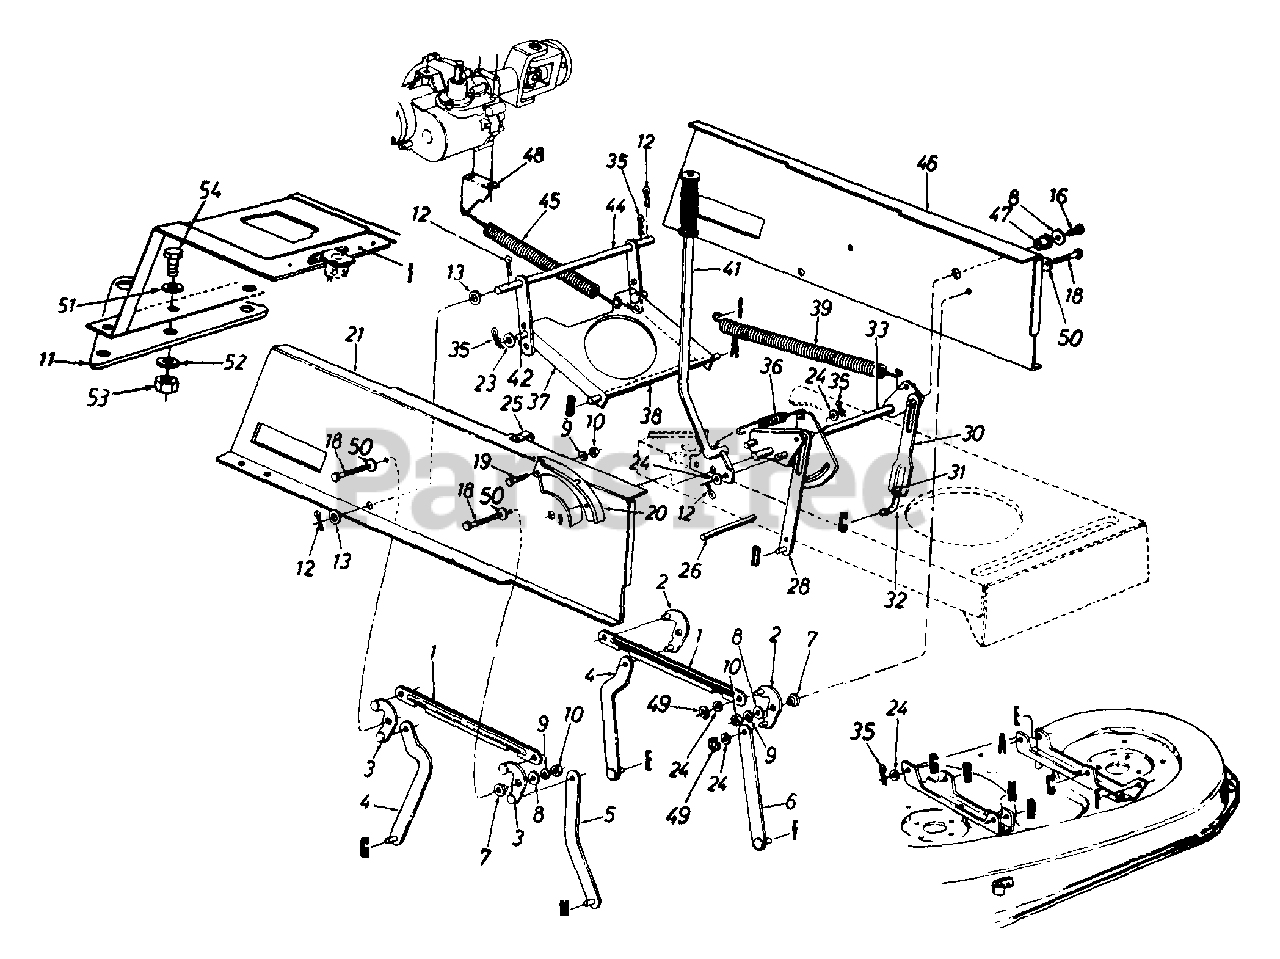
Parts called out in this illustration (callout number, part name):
3	Pivot Link Ass'y. - R.H.
7	Shld. Spacer .318" I.D.
8	Fl-Wash. .344" I.D. x .62" O.D.
9	L-Wash. 5/16" I.D.
10	Hex Nut 5/16-18 Thd.
11	Hitch Plate Extension
12	Cotter Pin 1/8" Dia.
13	Fl-Wash. .635" I.D. x 1.0" O.D.
16	Hex Wash. TT-Tap Scr. 5/16-18 x .75" Lg.
18	Hex Wash. Hd. Scr. 5/16-18 x .875" Lg.
19	Hex Bolt 5/16-18 x .75" Lg.
20	Index Brkt.
21	Upper Frame - R.H.
23	Fl-Wash. .385" I.D. x .87" O.D.
24	Fl-Wash. .531" I.D. x .93" O.D.
26	Running Board Rod
31	Hex Nut 1/2-20 Thd. (Gr. 5)
32	Lift Link Adjuster
33	Lift Shaft Ass'y.
35	Inter. Cotter Pin 3/8" Dia.
36	Extension Spring
39	Extension Spring
41	Deck Lift Handle Ass'y.
42	Weld Pin
44	Stabilizer Shaft Ass'y.
45	Extension Spring 7.58" Lg.
46	Upper Frame - L.H.
47	Flange Brg. .632" I.D.
49	"E"-Ring
50	Bell-Wash. .325" I.D.
51	Bell-Wash. .46" I.D.
52	Fl-Wash. .469" I.D.
53	Hex Nut 7/16-14 Thd. (Gr. 5)
54	Hex Bolt 7/16-14 x 1" Lg.
